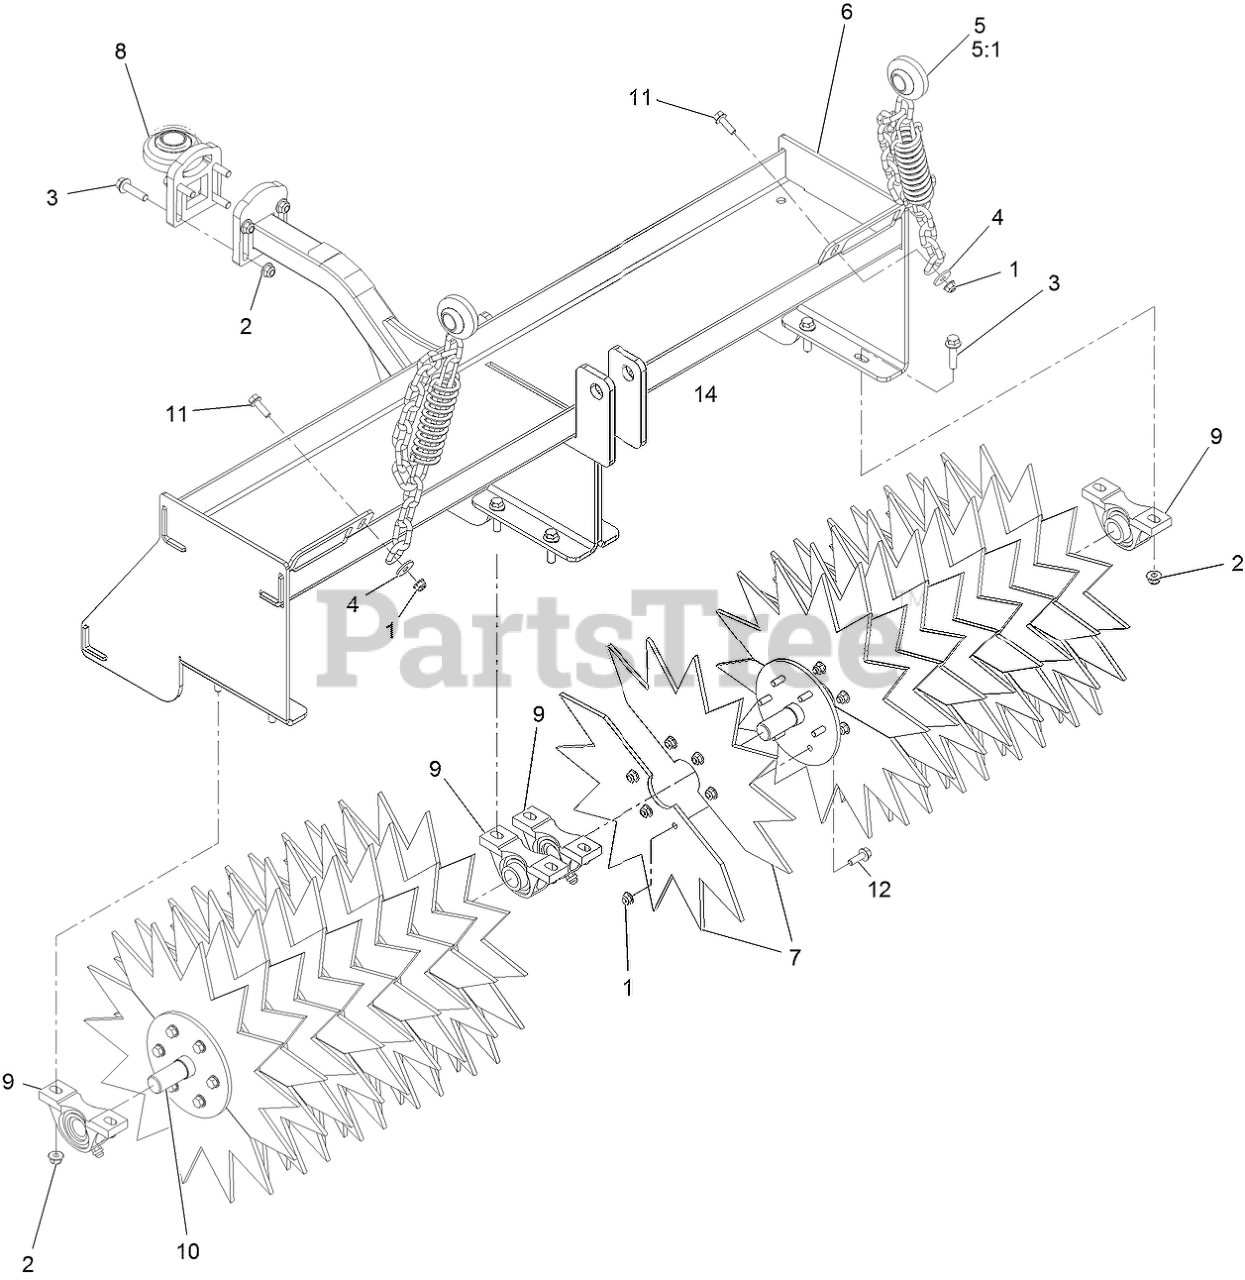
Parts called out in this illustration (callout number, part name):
1	NUT-HF, NI
2	NUT-HF, NI
3	SCREW-HHF
4	WASHER-FLAT
5	SWIVEL-CHAIN ASM
5:1	Z-PLUG DRAWBAR SPRING
6	HEAD-AERATION, 40""
7	STAR, SPIKER HEAD
8	MOUNT-SWIVEL BRG,AER HEAD
9	PILLOW BLOCK BEARING
10	DISC-SPYKER HEAD
11	SCREW-HH
12	SCREW-HHF
14	DECAL-WARNING
